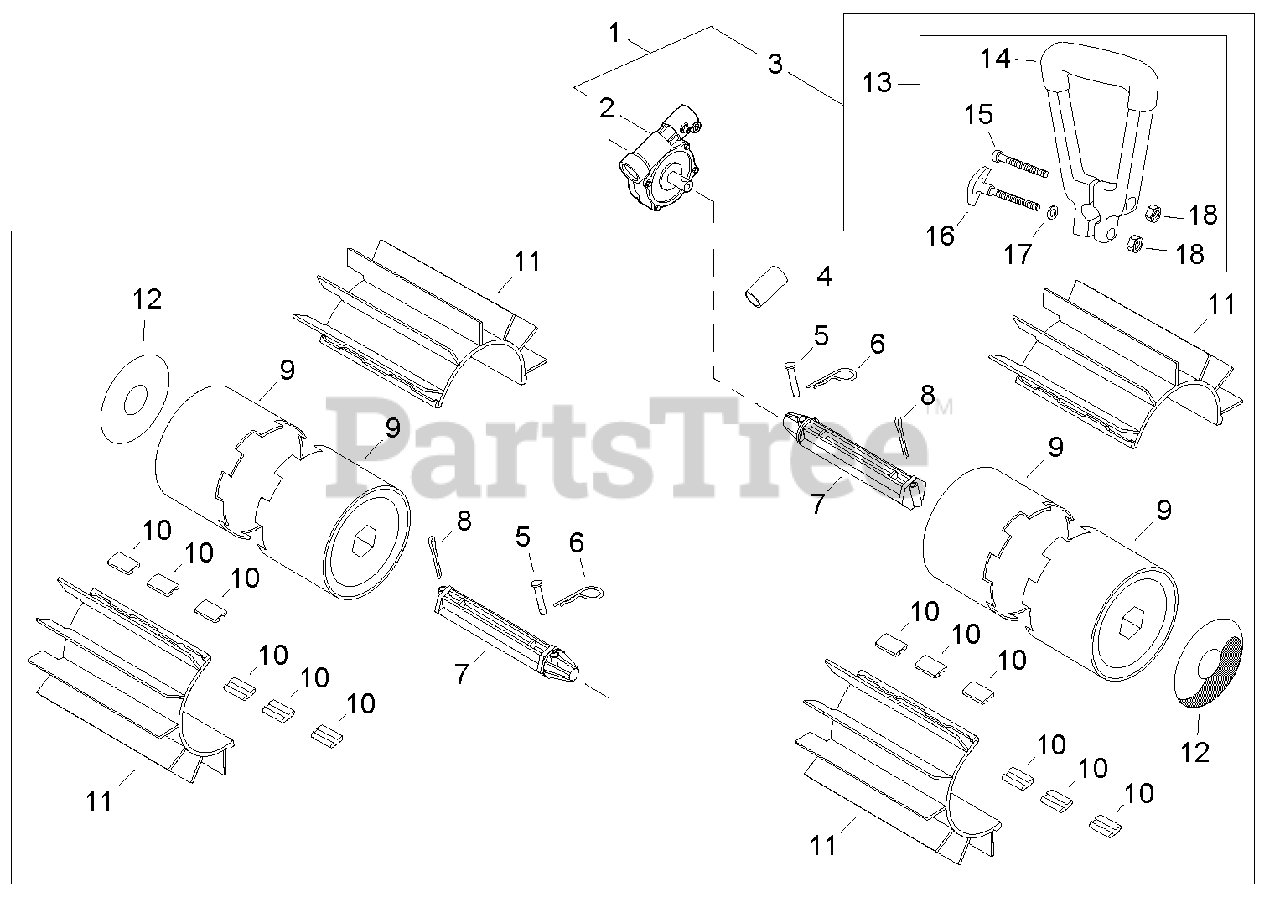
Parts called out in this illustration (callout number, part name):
1	B & D ASSY WITH GEARCASE ASSY
2	GEAR CASE ASSY
3	B & D ASSY WITHOUT GEARCASE
4	CAP, MAIN PIPE
5	PIN - CLEVIS
6	PIN - HITCH
8	PIN, SPLIT
9	HUB, DRUM
10	CLIP, BELT
11	BELT
13	HANDLE ASSY
14	HANDLE - FRONT
15	SCREW
16	THUMBSCREW
17	WASHER
18	NUT - 6
